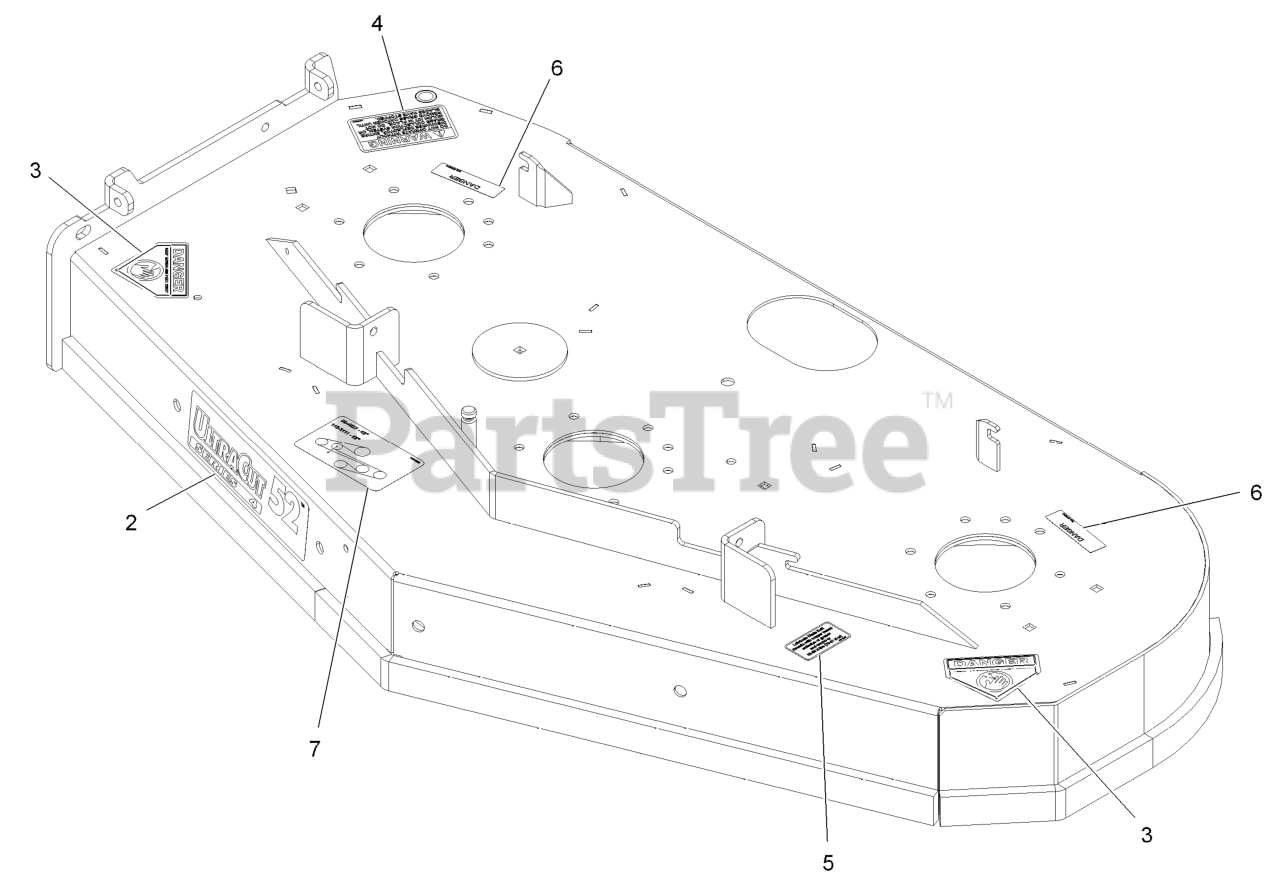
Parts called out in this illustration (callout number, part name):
2	DECAL,ULTRACUT 52 SERIES
3	DECAL-DANGER
4	DECAL-WARNING, DISCHARGE
5	DECAL,BOLT TORQUE
6	DECAL-COVER, MISSING
7	DECAL-BELT ROUTING
